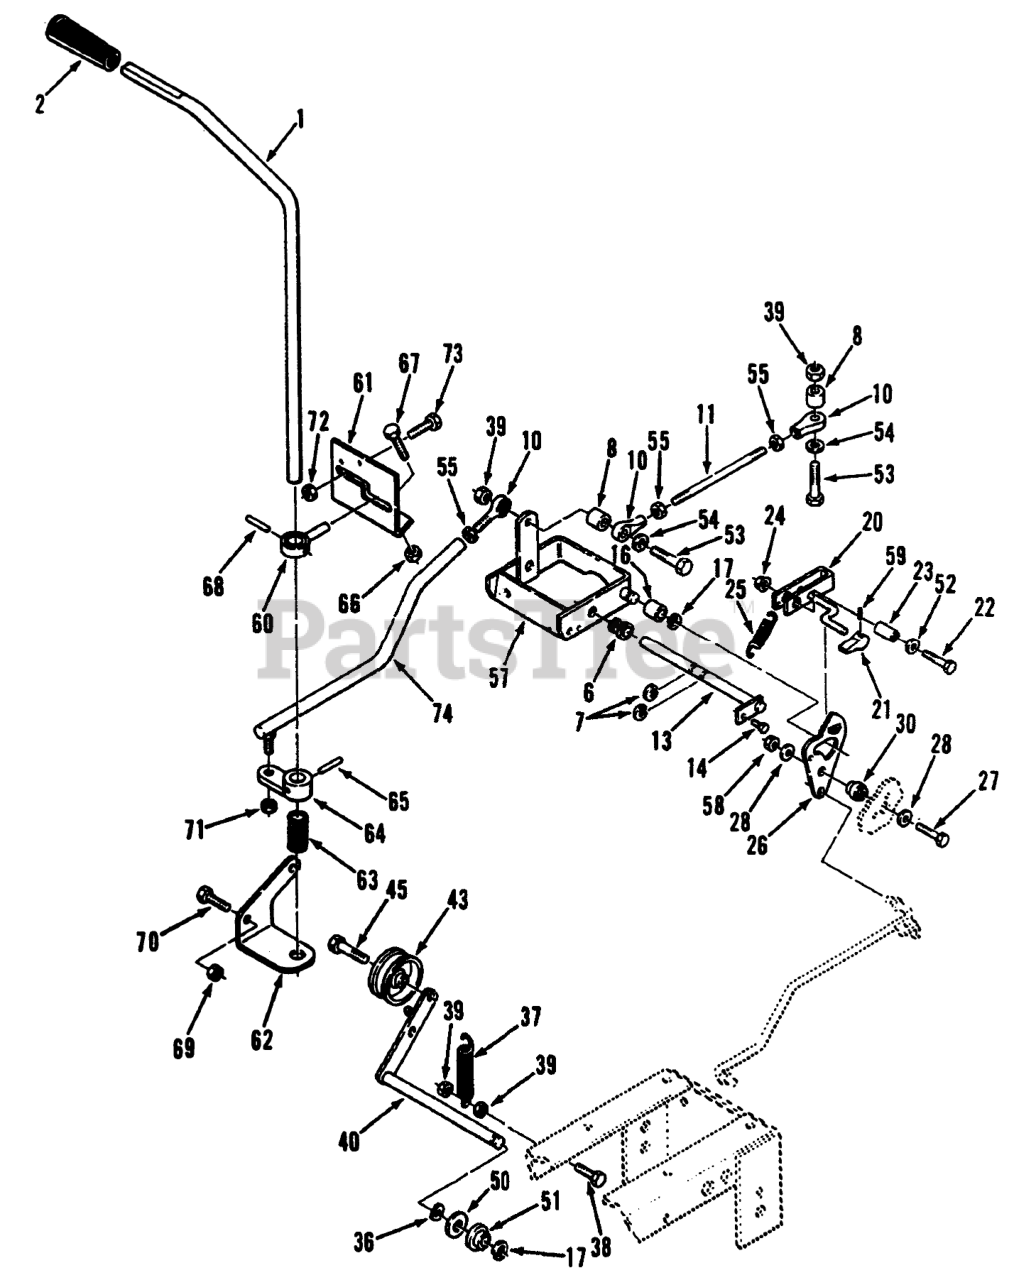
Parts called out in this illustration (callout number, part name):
1	ROD-MOTION CONTROL
2	Knob-Motion Control
6	NYLINER BUSHING
7	SCREW-HH
8	Spacer
10	ROD END, 1/4-28
11	ROD-CONTROL
13	ASSY-ROD CAM PIVOT
14	SCREW
16	BEARING-CAM RETURN
17	RING-RETAINING, EXTERNAL
20	Lever-Parking Brake
21	KNOB-PARKING BRAKE
22	SCREW-HH
23	SPACER
24	LOCKNUT-FLANGE
25	Spring
26	Cam Plate
27	SCREW-HH
28	WASHER-FLAT
30	Spacer
36	WASHER-WAVE
37	SPRING-EXTENSION
38	SCREW-HH
39	NUT-LOCK, NI
40	WLDMT-IDLER ARM
43	PULLEY-IDLER
45	BOLT-SPECIAL HEX
50	Washer
51	BUSHING-FLANGED
52	WASHER-FLAT
53	SCREW-HH
54	WASHER-FLAT
55	NUT-JAM
57	Cam Comtrol
58	NUT-LOCK, NI
59	PIN-SPIROL 3/32X5/8
60	GUIDE-CONTROL
61	BRKT-CONTROL
62	Bracket-Control
63	SPRING-COMPRESSION
64	ARM-CONTROL
65	PIN-SPECIAL
66	NUT-LOCK, NI
67	SCREW-HH
68	SPIROL PIN 7/32X7/8
69	NUT-LOCK, NI
70	SCREW-HH
71	NUT-LOCK
72	NUT-LOCK, NI
73	SCREW-HH
74	ASSY-ROD & BALL JOINT
